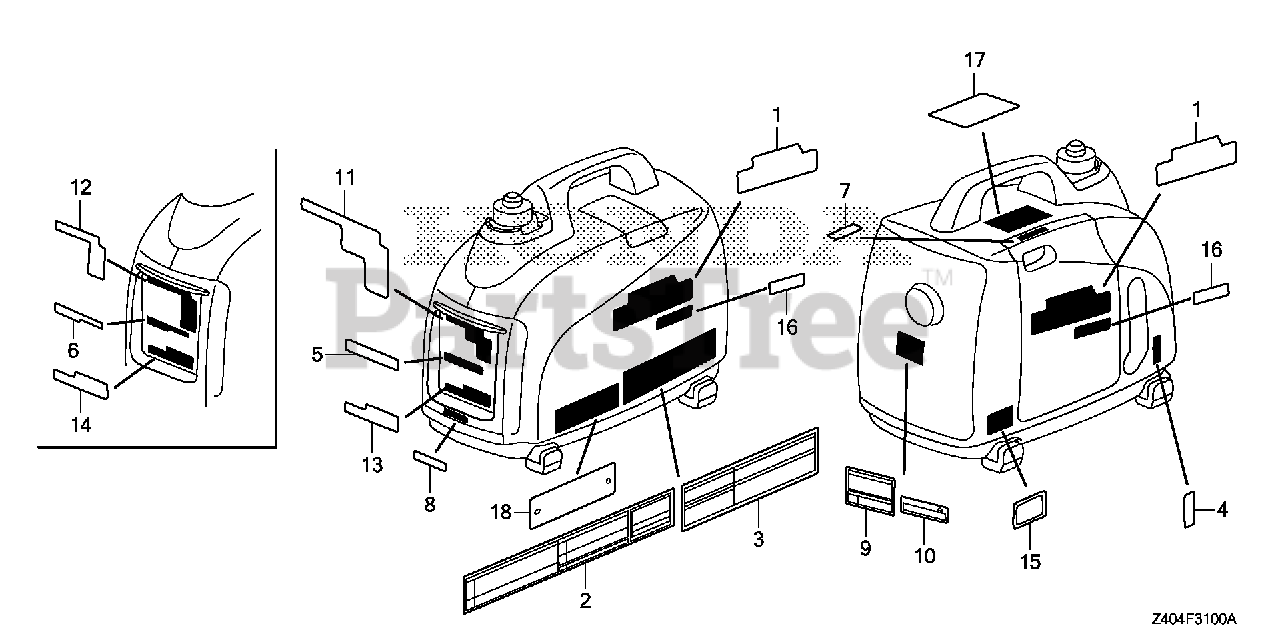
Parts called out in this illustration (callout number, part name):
1	EMBLEM (EU1000i)
2	MARK, CAUTION
4	MARK, ENGINE SWITCH
5	MARK, D.C. CAUTION
7	MARK, CHOKE
8	MARK, HONDA
9	MARK, EX. WARNING (E)
11	MARK, A.C. CAUTION
13	MARK, CIRCUIT PROTECTOR
15	MARK, OIL CAUTION
17	MARK, CPSC (CO CAUTION)
